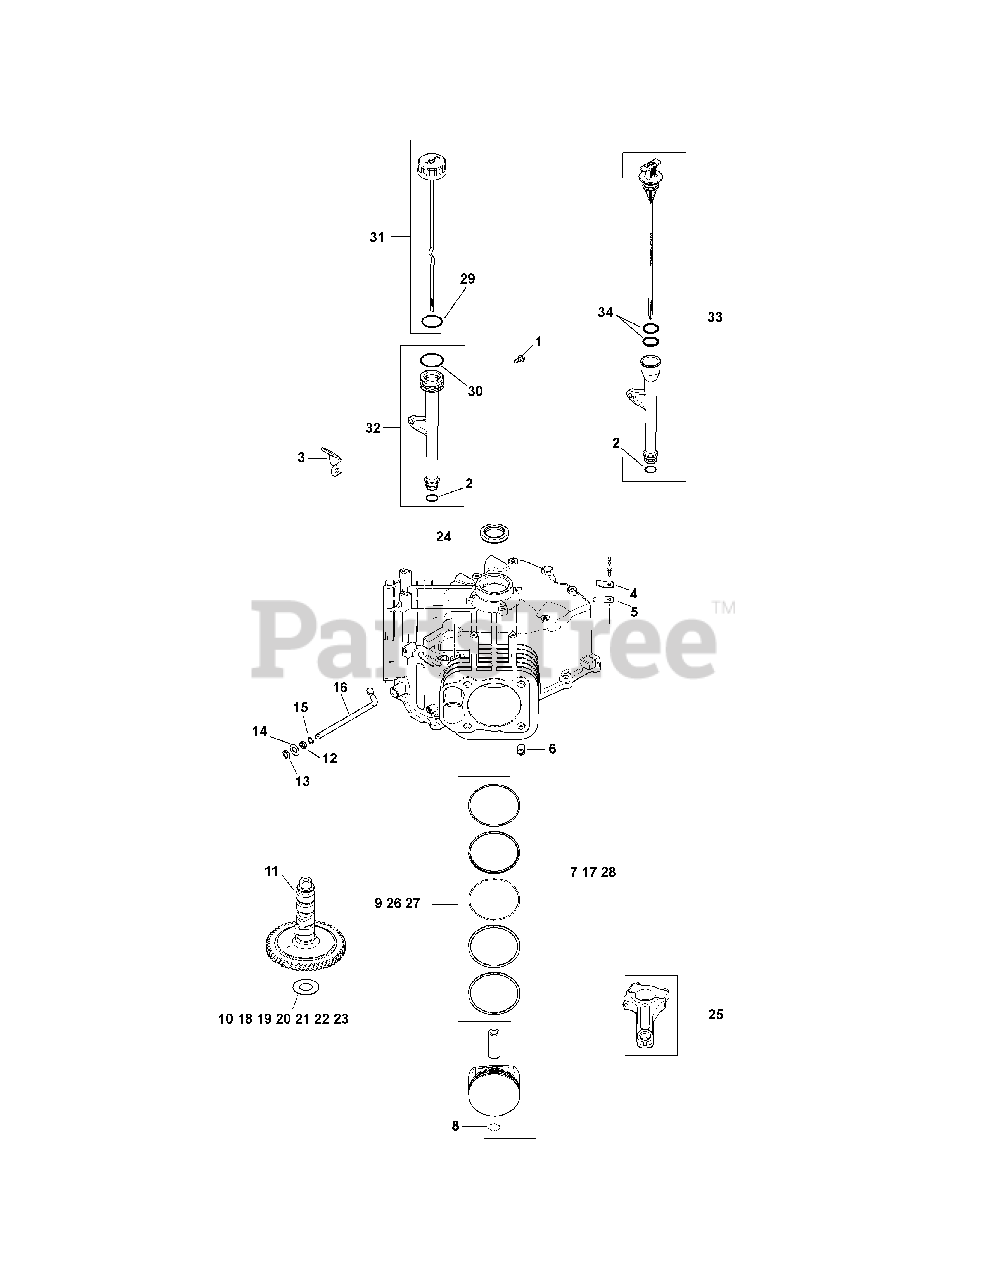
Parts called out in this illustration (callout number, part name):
1	Flg. Thd. Frm. Screw, M5 X 0.8 X 13
2	Lower Oil Fill Tube O-Ring
3	Oil Fill Tube Bracket
4	Breather Reed Retainer
5	Breather Reed
7	Piston Kit w/ Ring Set (Inc. 8, 26)
8	Piston Pin Retainer
9	Ring Set (.08)
10	Camshaft Shim (White .028")
11	Camshaft Kit (Inc. KH-25-357-14-S)
12	Governor Cross Shaft Seal
13	Ring Retainer
14	Flat Washer, 9 Mm
15	Flat Washer, 11/32
16	Governor Cross Shaft
17	Piston Kit w/ Ring Set (0.25) 83mm
18	Camshaft Shim (Blue .03")
19	Camshaft Shim (Red .032")
20	Camshaft Shim (Yellow .034")
21	Camshaft Shim (Green .036")
22	Camshaft Shim (Gray .038")
23	Camshaft Shim (Black .04")
24	Oil Seal (Helix Lip)
25	Connecting Rod (Std)
26	Ring Set (Std)
27	Ring Set (.25)
28	Piston Kit w/ Ring Set (0.08) 83mm (Inc. 8 & 9)
29	Dipstick O-Ring
30	Upper Oil Fill Tube O-Ring
31	Dipstick Assembly (Inc. 29)
32	Tube Assembly (Inc. 2, 30)
33	Dipstick & Tube Kit (Inc. 2 & 29)
34	O-Ring
